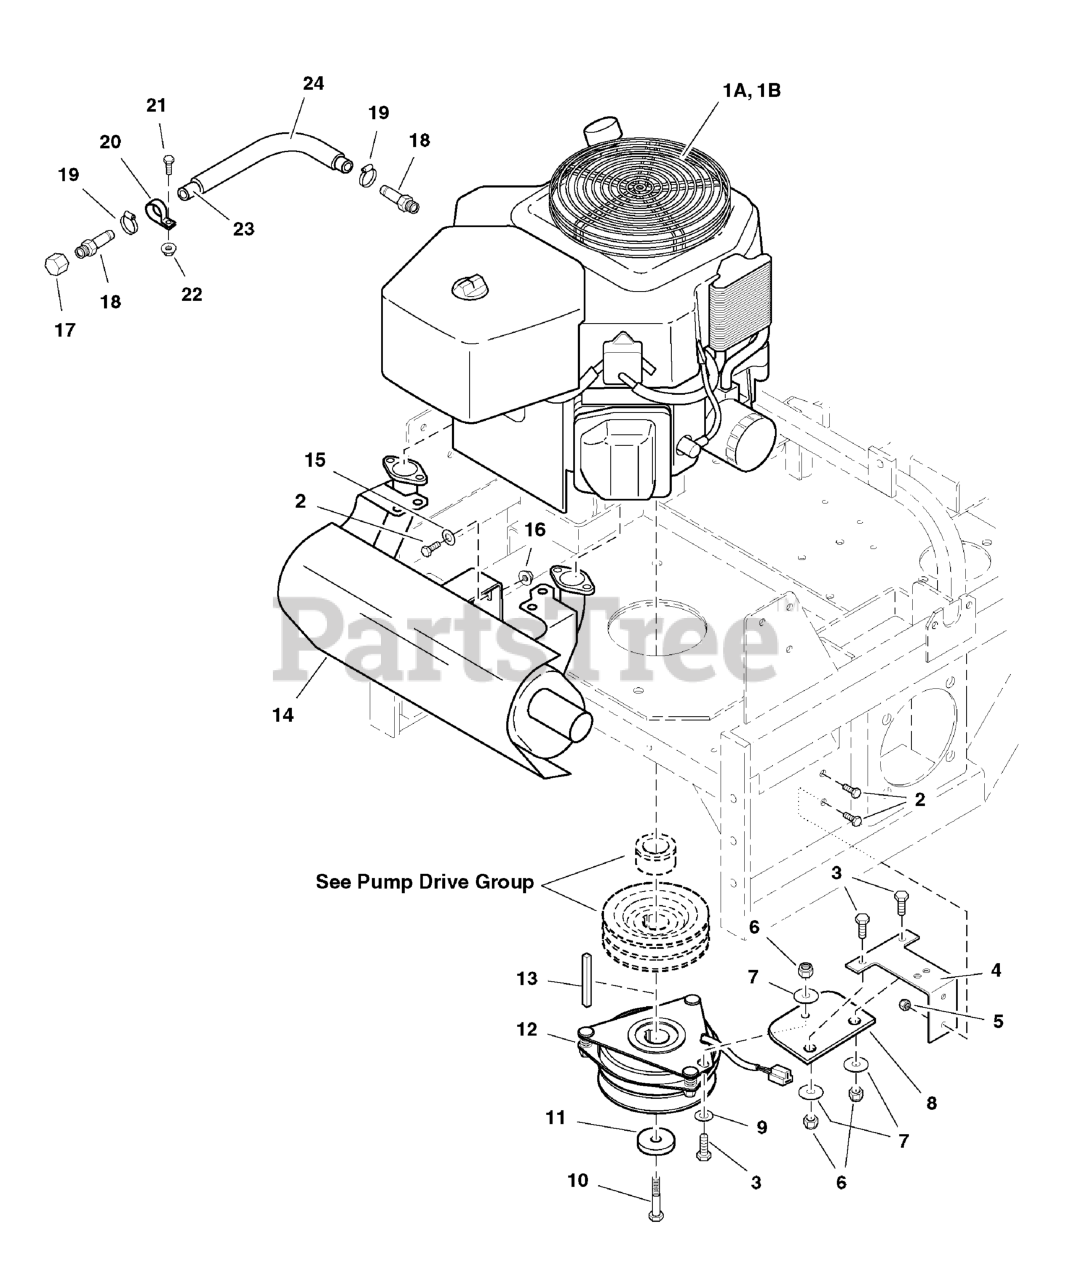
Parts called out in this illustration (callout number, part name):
1	ENGINE, Kohler
2	BOLT, 5/16-18 X 3/4 GD5
3	BOLT, 3/8-16 X 1" GD5 CZ
4	CLUTCH ANCHOR
5	NUT, 5/16-18 Hex Nylon Lock
6	NUT, 3/8-16 HEX NYLON LOCK
7	WASHER, 3/8" Fender
8	CLUTCH ANCHOR PAD
9	WASHER, 3/8 SAE
10	CRANKSHAFT BOLT, 7/16 x 2
11	SPACER, .45 x 1.88 x .38
12	ELECTRIC CLUTCH
13	KEY, 1/4 SQ. X 3-1/2
14	MUFFLER
15	WASHER, 5/16" SAE
16	NUT, 5/16-18 HEX SERRATED FLANGE (SMALL)
17	CAP, 3/8 NPT
18	FITTING, 3/8NPT-1/2" Hose, Straight
19	CLAMP, #6 Hose
20	CLAMP, Vinyl
21	BOLT, 1/4-20 x 3/4
22	NUT, 1/4-20 HEX SERR. FLANGE
23	HOSE, 13"
24	WIRE LOOM, 12"
